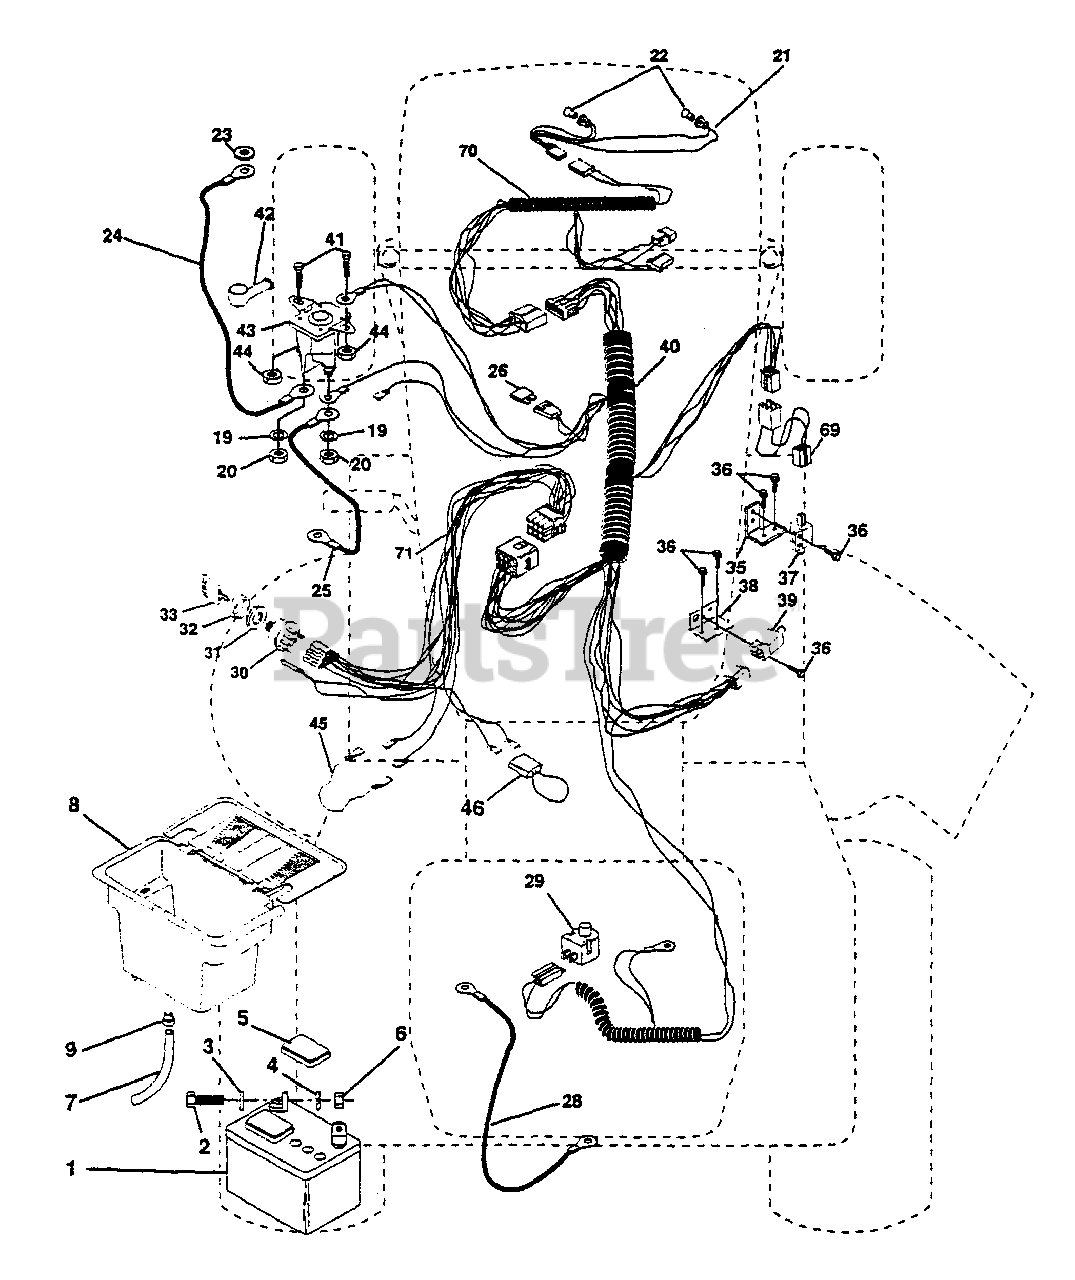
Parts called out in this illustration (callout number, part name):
1	Battery 12 Volt 25 AMP
2	Bolt Hex Hd 1/4-20unc X 3/4
3	Washer 9/32 X 5/8 X 16 Ga.
4	Washer Lock Hvy Helical 1/4
5	Caps Battery 20/25/30 AMP
6	Nut Fin Hex 1/4-20 Unc
7	Tube Plastic 12"
8	Case Battery Hng Mech W/lid
9	Clamp Hose Olive
19	Washer Lock 1/4
20	Nut Jam Hex 1/4-20 Unc
21	Harness Asm Light W/4152j
22	Bulb Light #1156
23	Washer Lock Internal Tooth 1/4
24	Cable Battery 6 Ga 11" red
25	Cable Battery 6 Ga 43" red
26	Fuse 30 AMP Auto Green
28	Cable Ground 6 Ga 12' black
29	Switch Plunger Nc Gray
30	Switch Ign 4 pos w/Lights
31	Nut Ignition
32	Cover Sw Ignition
33	Key Ign Modleded Generic
35	Bracket Switch Clutch
36	Screw Tap Hex #10-24unc X 1/2
37	Switch Intlk Clutch Red 2 Term
38	Bracket, Switch, Interlock
39	Switch Intlk Clutch Red 4 Term
40	Harness Chassis LT PL Mech
41	Bolt Blk Fin Hex 1/4 - 20 x 1/2
42	Cover Terminal Red
43	Solenoid
44	Nut Keps Hex 1/4-20 Unc
45	Adapter Ammeter Rectangular
46	Protection Wire Loop
69	Harness Adapter Serv Geardrive
70	Harness, Eng.
71	Harness Dash Lt Private Lbl
